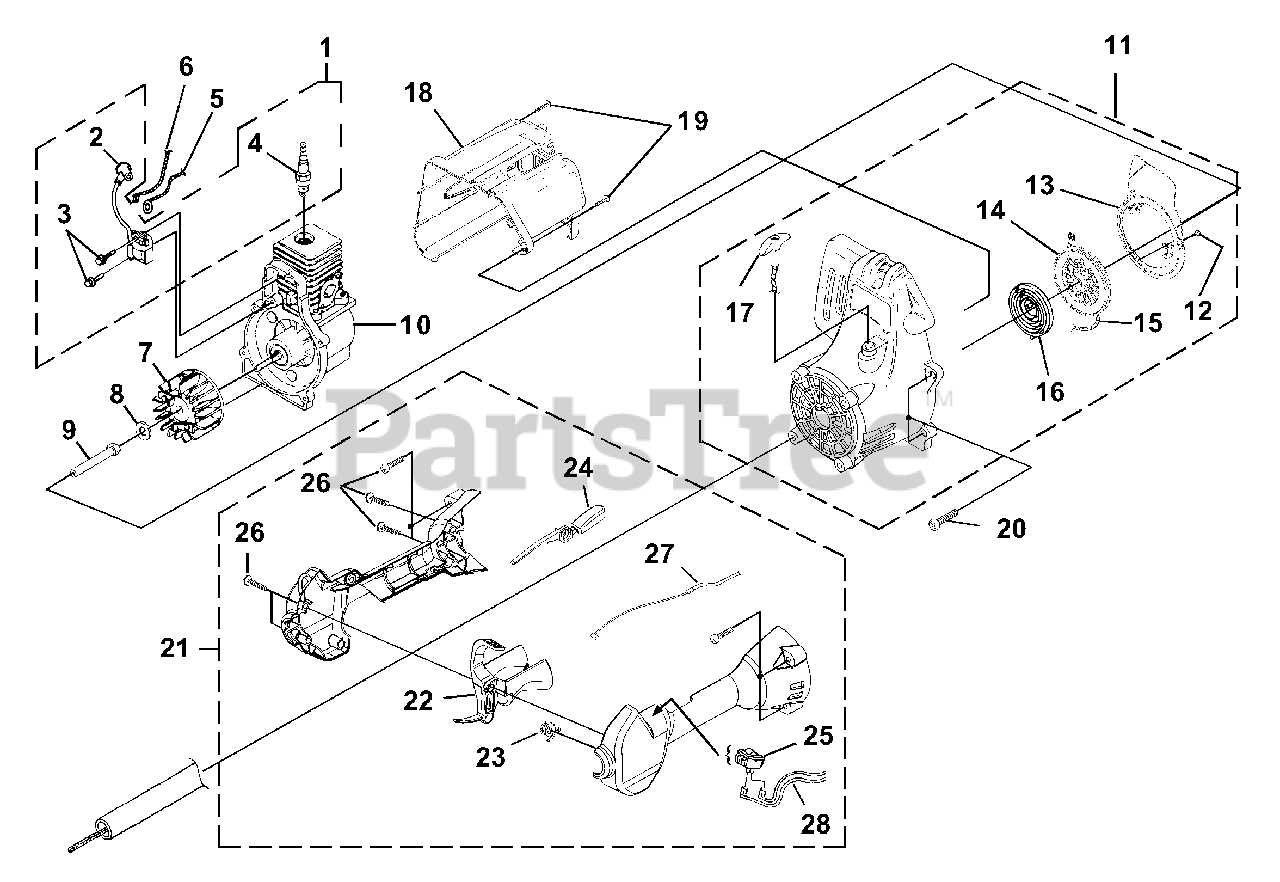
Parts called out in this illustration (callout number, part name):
1	IGNITION KIT
2	TERMINAL & COVER
3	SCREW-Taptite (8-32 X 1")
4	SPARK PLUG (RDJ-7Y
5	LEAD-Electrical
6	LEAD-Electrical
7	ROTOR KIT
8	WASHER-Flat
9	CONNECTOR AND DRUM
10	SHORT BLOCK
11	STARTER ASSEMBLY
12	SCREW-Thread Form (8-16 X 1/2")
13	BAFFLE-Air
14	PULLEY-Starter
15	ROPE-Starter (42")
16	SPRING & CONTAINER
17	GRIP-Starter (Yellow)
18	HOUSING-Rear Kit
19	SCREW-Plastite (10-14 X 3/4")
20	SCREW-Taptite (10-24 X 3/4")
21	CONTROL HANDLE ASSY.
22	TRIGGER-Throttle
23	SPRING
24	THROTTLE INTERLOCK
25	SWITCH
26	SCREW-Taptite (10-14 X 1")
27	CABLE-Throttle
28	LEAD-Electrical
